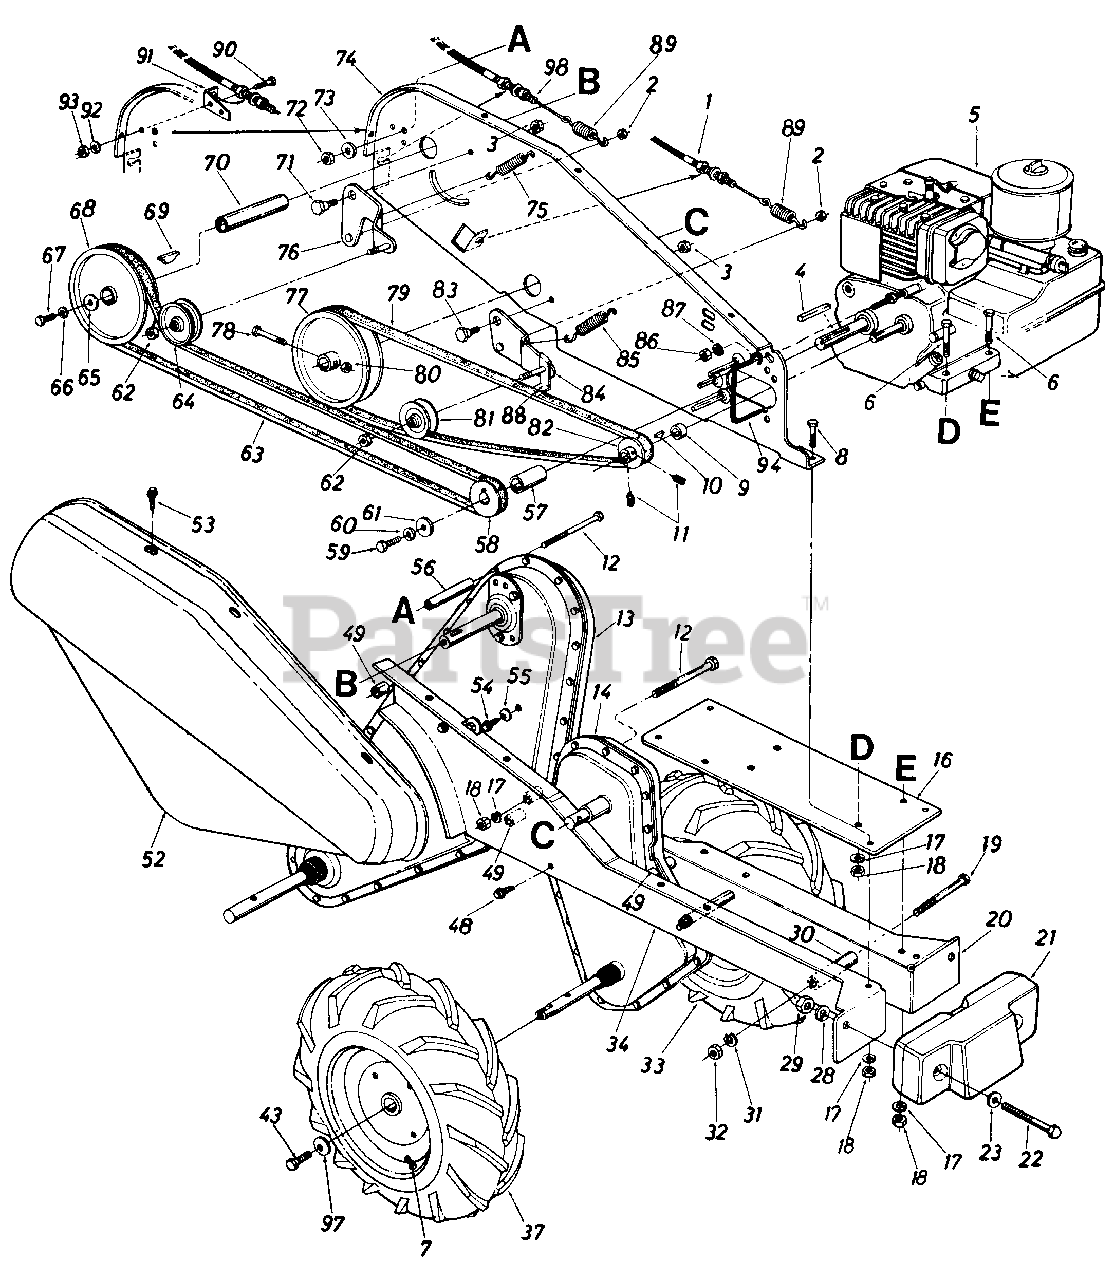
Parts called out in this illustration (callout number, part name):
1	Clutch Control Cable
2	Hex Cent. L-Nut 1/4-20 Thd.
3	Hex Cent. L-Nut 3/8-16 Thd.
4	Sq. Key 3/16" Dia. x .75
5	Engine
6	Hex Bolt 5/16-18 x 1.50" Lg.
7	Air Valve
8	Hex Bolt 5/16-18 x .75" Lg.
9	Spacer .51" I.D. x 314" O.D. x.39" Lg.
10	Hi-Pro Key #5 Woodruff
11	Set Scr. 1/4-28 x .25" Lg.
12	Hex Bolt 5/16-18 x 3.0" Lg.
18	Hex Nut 5/16-18 Thd.
19	Hex Bolt 3/8-24 x 3.0" Lg.
22	Hex Bolt 1/2-13 x 4.0" Lg.
23	Fl-Wash. 1/2" I.D. x 1.0" O.D.
28	L-Wash. 1/2" I.D.
29	Hex Nut 1/2-13 Thd.
30	Spacer 3/8" I.D. x 5/8" O.D. x 2.18" Lg.
31	L-Wash. 3/8" I.D.
32	Hex Nut 3/8-24 Thd.
33	Comp. Wheel Ass'y.-L.H.
48	Hex Wash. Self-Tap Scr. 5/16-24 x .50" Lg.
49	Spacer 5/16" I.D. x 16 Ga. x 96n Lg
54	Hex Wash. S-Tap Scr. 1/4-20 0 x 3l8n Lg.
55	Bell-Wash. 1/4" I.D.
56	Spacer 3/8" I.D. x 1/2" O.D. x 2.0" Lg.
57	Spacer 3/4" I.D. x 1.12" O.D. x 1.56" Lg.
58	1/2" "V"-4L Pulley 3/4" I.D. x 2.59" O.D.
59	Hex Bolt 5/16-24 x 1.0" Lg.
60	L-Wash. 5/16" l.D.
61	Fl-Wash. 5/16" I.D. x 1.25" O.D.
62	Hex L-Nut 3/8-24 Thd.
63	"V"-Belt
64	Fl-ldler Pulley 3.75n O.D. x 3/8" I.D.
65	Fl-Wash. .25" I.D. x .93" O.D. x .120
66	L-Wash. 1/4" I.D.
67	Hex Bolt 1/4-28 x .75" Lg.
68	Split Pulley 6n Dia. x 5/8" I.D.
69	Hi-Pro Key
71	Shld. Bolt 1/2" Dia. x .210n Lg.
72	Hex Nut 5/16-18 Thd.
73	L-Wash. 5/16" l.D.
74	Side Plate Ass'y.
75	Ext. Spring .50" O.D. x 1.55" Lg.
76	Idler Bracket Ass'y.-Tines
77	Pulley 5n Dia. x 5/8" I.D.
78	Hex Bolt 1/4-28 x 1.50n Lg.
79	"V"-Belt
80	Hex Cent. L-Nut 1/4-28 Thd.
81	"V"-Idler Pulley 2-5/8" O.D.
82	1/2" "V"-Pulley 21/4" O.D. x 50" I.D.
83	Shld. Bolt 1/2" Dia. x .160" Lg.
84	Idler Bracket Ass'y-Wheels
85	Ext. Spring .50n O.D. x 1.55n Lg.
86	Hex Nut 1/4-20 Thd.
87	Bell-Wash. 1/4" I.D.
88	Belt Keeper Ass'y.
90	Hex Bolt 5/16-18 x .75
91	Clutch Cable Brkt.
92	Lock Washer 5/16n l.D.
93	Hex Nut 5/16-18 Thd.
94	Belt Keeper
97	Bell-Wash. 5/16" I.D.
98	Clutch Control Cable
